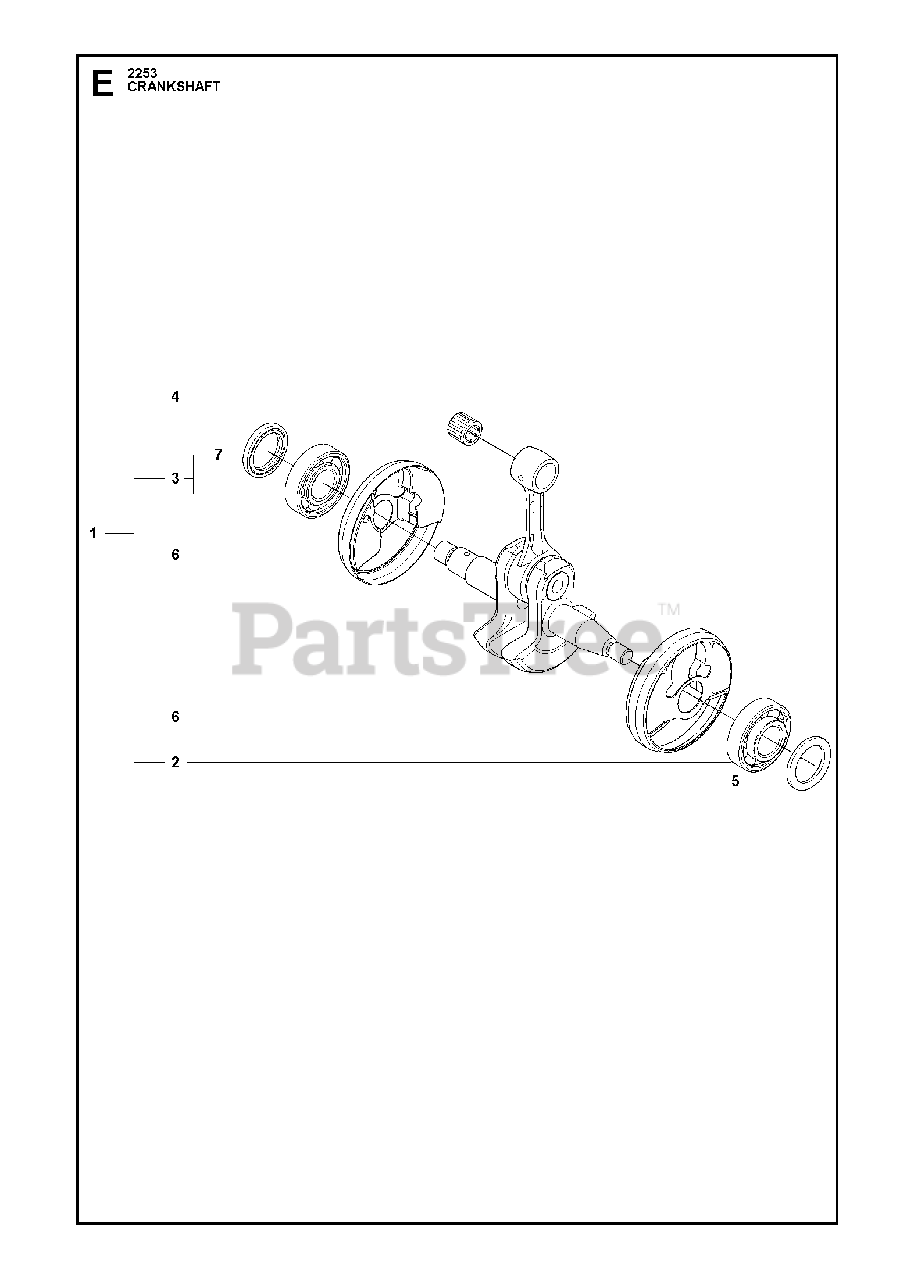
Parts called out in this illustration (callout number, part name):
1	CRANKSHAFT ASSY
2	BALL BEARING
3	BALL BEARING
4	NEEDLE BEARING
5	RADIAL SEAL
6	CUP
7	RADIAL SEAL
